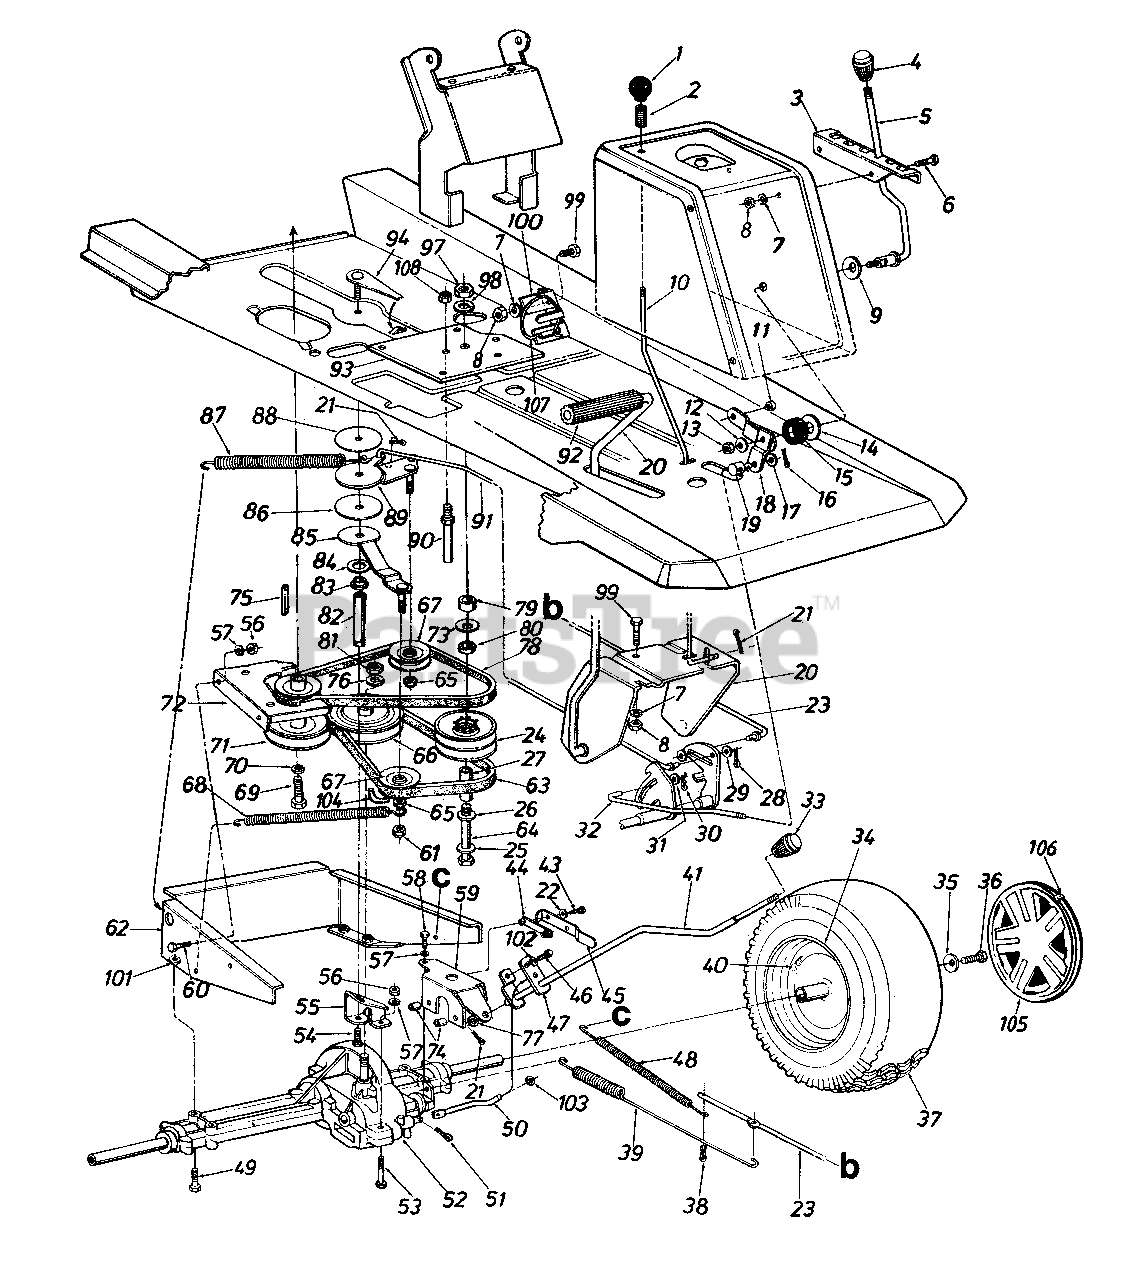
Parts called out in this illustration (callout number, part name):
1	Ball Knob 1/4-20 Thd. 1.25"
2	Compression Spring
5	Speed Control Lever
6	Truss Mach. Scr. 5/16-18 x.75"
7	L-Wash. 5/16" I.D.
8	Hex Nut 5/16-18 Thd.
9	Bell-Wash. .345" I.D. x .88"
10	Brake Locking Rod (560)
12	Bell-Wash. .345" I.D. x .08"
13	Hex Cent. L-Nut 5/16-18 Thd.
14	Fl-Wash. .531" I.D. x 1.25" O.D.
15	Rubber Washer (560)
16	Intern. Cotter Pin 1/2" Dia.
17	Fl-Wash. .34" I.D. x .68" O.D.
18	Speed Control Lever Brkt. Ass'y.
19	Ferrule-Engagement
20	Clutch/Brake Pedal Ass'y.
21	Cotter Pin 3/32" Dia. x .75"
22	Plastic Washer
23	Brake Rod
24	Variable Speed Pulley Ass'y.
25	Fl-Wash. .4" I.D. x 1.25" O.D.
26	Thrust Brg. 1.25" O.D. x .56"
27	Spacer Sleeve 2.71"
28	Cotter Pin 1/8" Dia. x 1.25"
29	Fl-Wash. .34" I.D. x .60" O.D.
30	Intern. Cot-Pin 5/16" Dia.
31	Fl-Wash. .34" I.D. x .60" O.D.
32	Speed Control Link
33	Shift Knob
35	Bell Wash. .345" I.D. x .88"
36	Hex L-Bolt 5/16-24 x .75" Lg.
38	Cotter Pin 1/8" Dia. x 1.25"
39	Extension Spring 17.0" Lg.
40	Air Valve
44	Insulator Nut
45	Spring Switch
46	Hex Bolt 1/4-20 x .50" Lg.
47	Shift Lever Adjusting Link
48	Ext. Spring 8 1/4" Lg.
49	Hex Bolt 5/16-18 x 2.5" Lg.
50	Shift Rod
51	Intern. Cotter Pin
52	Transaxle
53	Hex Bolt 1/4-20 x 1.75" Lg.
54	Hex Bolt 3/8-24 x .75" Lg.
57	L-Wash. 1/4" I.D.
58	TT-Tap Scr. 1/4-20 x 1.5" Lg.
59	Shift Lever Support Brkt.
60	Hex Bolt 1/4-20 x 1.00" Lg.
61	Hex L-Nut 3/8-24 Thd.
64	Hex Bolt 3/8-16 x 4.5" Lg.
65	Hex Ins. L-Nut 3/8-24 Thd.
66	V-Pulley
67	V-Belt Idler .38" I.D. x 3.06"
68	Ext. Spring .50" O.D. x 6.37"
69	Hex Bolt 7/16-20 x 1.00" Lg.
70	L-Wash. 7/16" I.D.
71	Engine Pulley
72	Upper Engine Belt Guard
73	Bell Wash. .4" I.D. x 1.12" O.D.
74	Spacer .256" I.D. x .50" O.D.
75	Sq.-Key 1/4" x 2.00" Lg.
76	Bell-Wash. .567" I.D. x 1.125"
77	Fl-Wash. .469" I.D. x .88" O.D.
78	V-Belt
79	Spacer 1.00" x .380" O.D.
80	Thrust Wash. .56" I.D. x 1.25"
81	Hex Jam Nut 9/16-18 Thd.
82	Torque Rod
83	Flange Bearing .378
84	Fl-Wash. .640" I.D. x 1.24"
85	Idler Bracket Ass'y.
86	Thrust Wash. .635" I.D.
87	Extension Spring 7.58" Lg.
88	Thrust Wash. .385" I.D.
89	Idler Bracket Ass'y. For Clutch
90	Belt Guard Pin 3/8-16 x 2.75" Lg.
91	Clutch Rod
92	Foot Pad
98	L-Wash. 3/8 Heavy Duty
99	Hex Bolt 5/16-18 x .75" Lg.
100	Speed Control Rod Brkt.
101	Hex Sems Nut 5/16-18 Thd.
102	Bell-Wash. .265" I.D. x .75" O.D.
103	Push on Retaining Ring
104	Belt Guard
105	Hub Cap-Beige
106	Spring Clip
107	Comp. Spring Clip
108	Hex Top L-Jam Nut 3/8-16 Thd.
